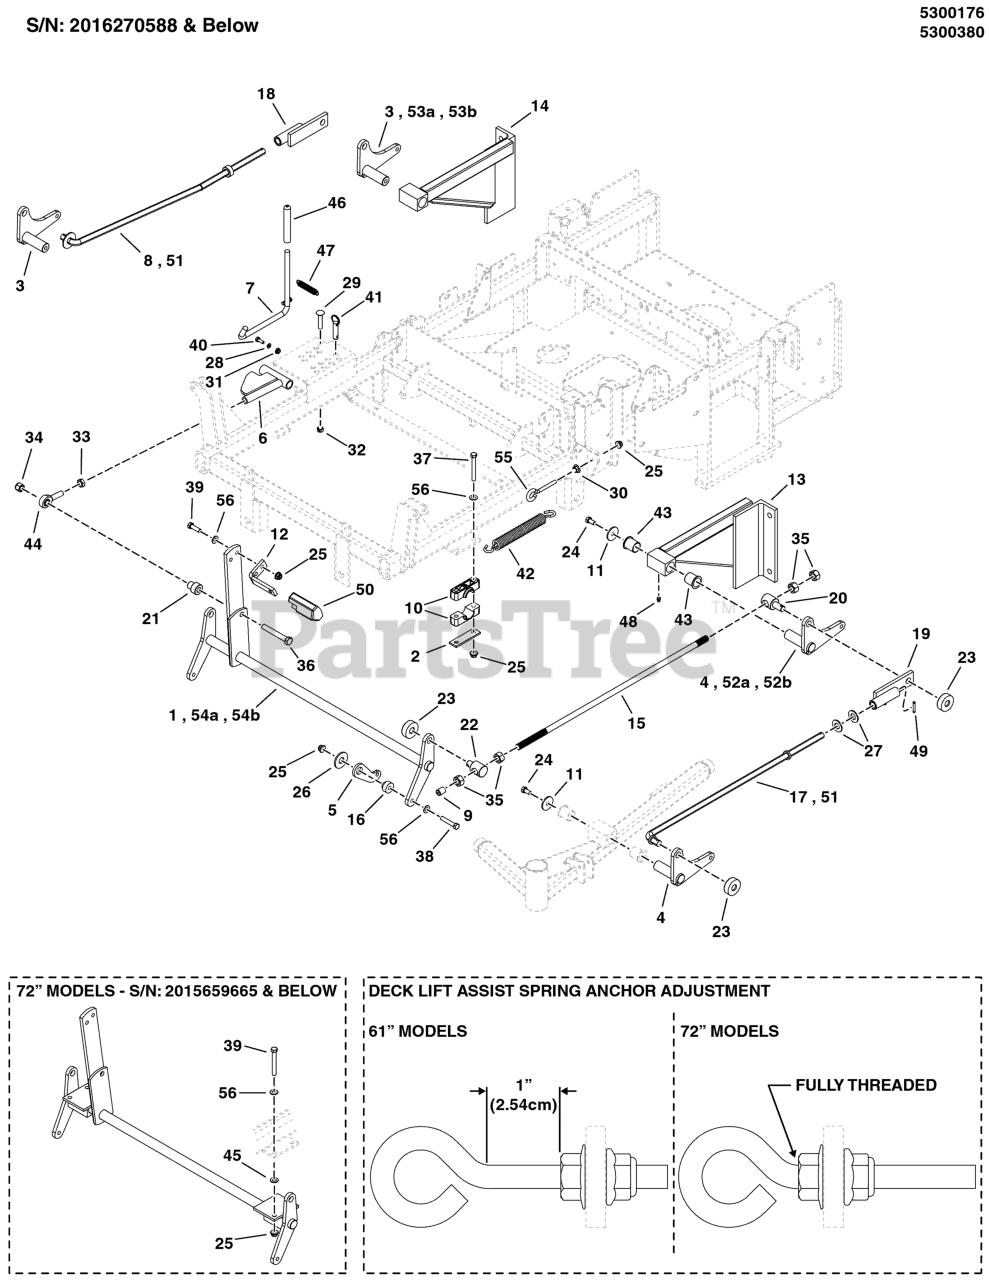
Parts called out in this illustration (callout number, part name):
1	WELD, DECK LIFT SHAFT IS3100Z - RED
2	PLATE, PIVOT BLOCK SUPPORT - BLK
4	PIVOT,DECK LIFT WELD,LEFT
5	LINK, SPRING, IS3100Z - RED
6	WELD, DECK ADJUST LINK - RED
7	WELD, DECK LIFT CONTROL, IS3000 - BLK
8	ROD, DECK LIFT, RH, IS3100-61
9	CAP, VINYL - .562 X .750 - BLK
10	PIVOT BLOCK, PLASTIC
11	WASHER, .390 X 1.50 X .109, YZ
12	PEDAL, FOOT - BLK
13	WELD, LIFT FRAME, LH
14	WELD, LIFT FRAME, RH
15	ROD, DECK ADJUSTMENT
16	BUSHING, DECK PIVOT
17	ROD, DECK LIFT ASSEMBLY, CZ
18	BAR, DECK LIFT WELD. - RH
19	BAR, DECK LIFT WELD. - LH
20	PIVOT, SPRING ROD
21	ADAPTER, CASTER AXLE, CZ
22	PIVOT, SPRING ROD
23	COLLAR, 5/8 SPLIT
24	BOLT, 3/8-16 X 3/4, PLT W/PATCH
25	NUT, 3/8-16 HEX NYLOCK FLANGE
26	WASHER, .39 X 2.00 X X .14
27	WASHER, 5/8 SAE
28	WASHER, 1/4 SAE
29	BOLT, 3/8-16 X 2, CARRIAGE
30	NUT, 3/8-16 HEX SERRATED FLANGE
31	NUT, 1/4-20 HEX SERR. FLANGE
32	NUT, 3/8-16 HEX SIDE LOCK
33	NUT, 1/2-20 HEX JAM
34	NUT, 1/2-13 HEX NYLON LOCK
35	NUT, 5/8-11 HEX
36	BOLT, 1/2-13 X 3-1/2, HEX HD, GD5, CZ (SV)
37	BOLT, 3/8-16 X 3" GD5 CZ
38	BOLT, 3/8-16 X 2, GD5, CZ
39	BOLT, 3/8-16 X 1-1/4" GD5 CZ
40	BOLT, 1/4-20 X 3/4 GD5 YZ
41	PIN, HITCH, 1/2 X 2.00 OAL, YP
42	SPRING-EXT, 1.00 ODX13.25LGX.177WR, BLK
43	BUSHING, 1.00 X 1.13 X 1.38, PLASTIC
44	BALL JOINT, 1/2-20, MALE
45	WASHER, 3/8 GD 9
46	GRIP, FOAM
47	SPRING-EXT, .500 OD X 3.50 LG X .058 WR
48	GREASE FITTING, 1/4-28 STRAIGHT
49	PIN-SPRING .188 X 1.00 PLN SAE 1095
50	PEDAL, Rubber
51	ROD, DECK LIFT
55	EYE BOLT, 3/8-16 X 2-1/2
56	WASHER, 3/8 SAE
